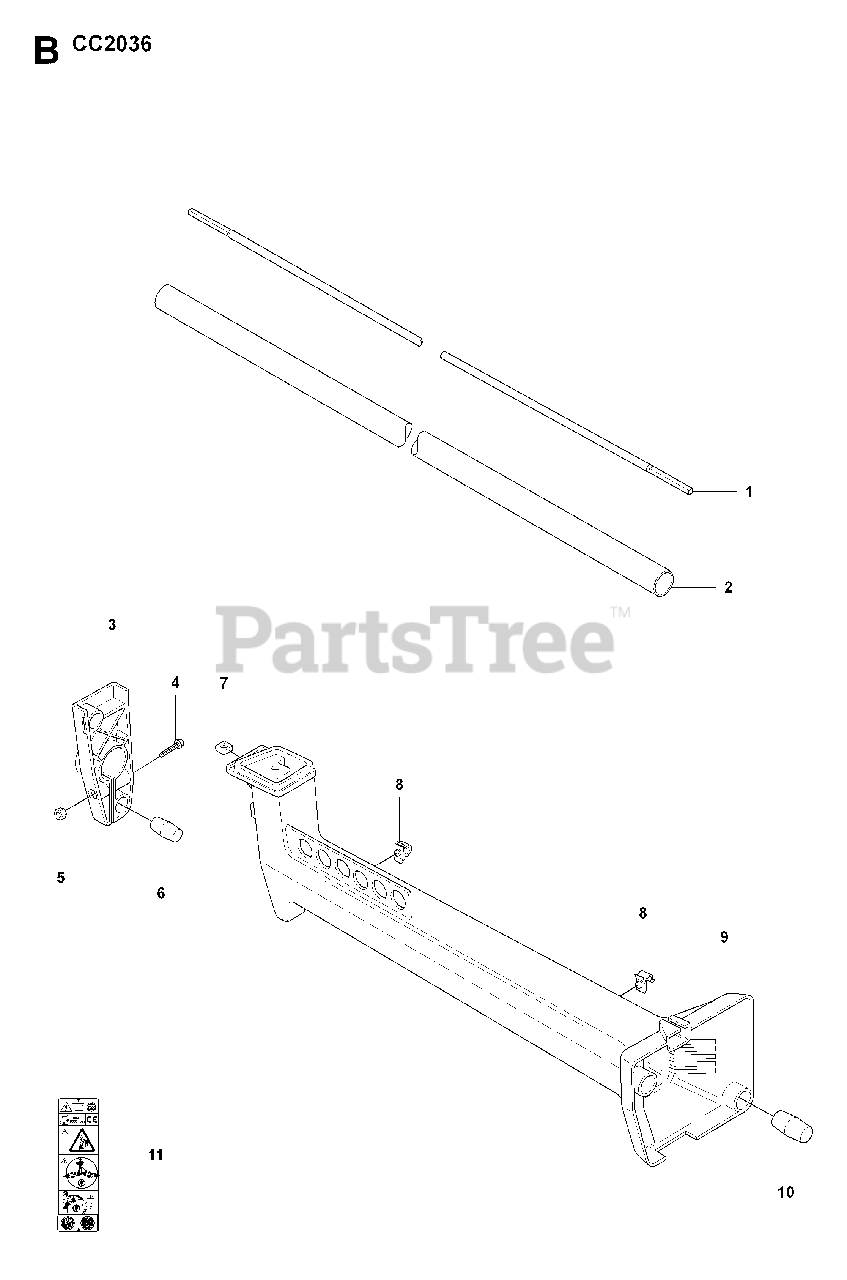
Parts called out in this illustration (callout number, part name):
4	SCREW
6	ABSORBER
9	SUPPORTINGTUBE
10	ABSORBER
11	DECAL
